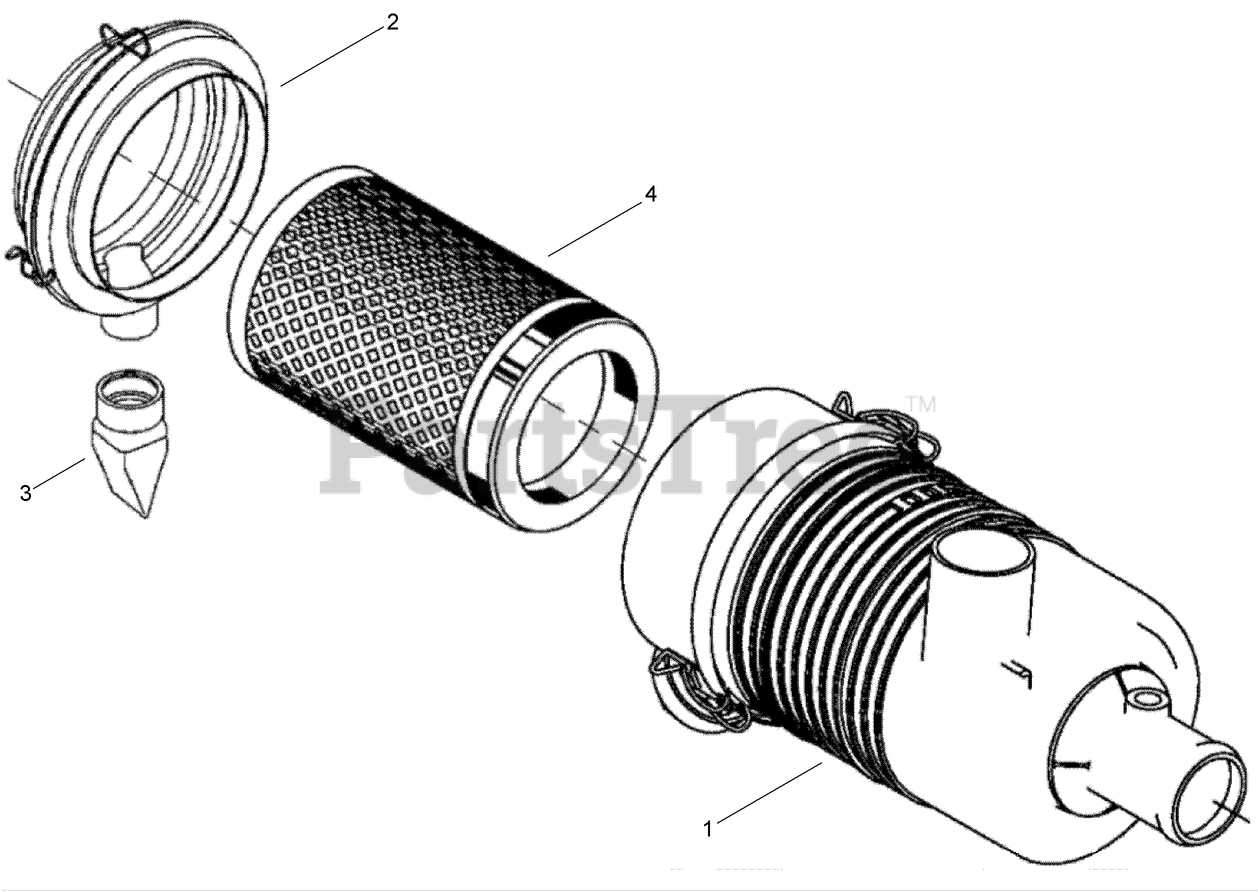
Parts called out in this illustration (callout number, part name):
1	HOUSING - Air Cleaner
2	COVER - Air Cleaner Housing
3	VALVE - Evacuator
4	COVER - Air Cleaner Housing
